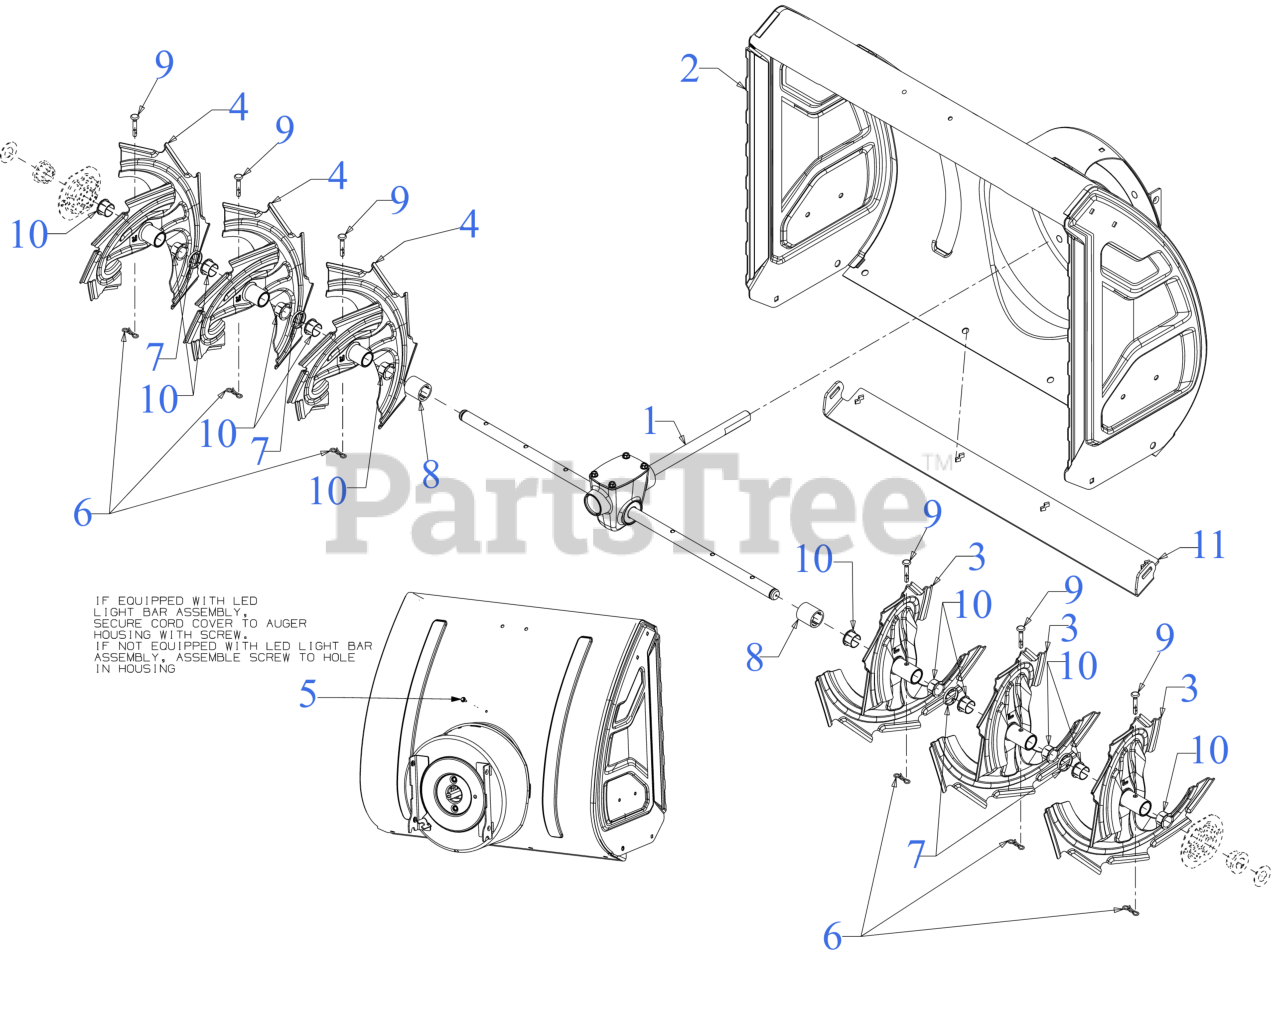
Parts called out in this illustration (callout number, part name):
1	30" AUGER GEARBOX ASSEMBLY
2	30" AUGER HOUSING ASSEMBLY HD W/LED
3	10T AUGER SPIRAL (LH)
4	10T AUGER SPIRAL (RH)
5	SCREW M6-1 x .625
6	BOW TIE COTTER PIN 1/4-5/16
7	SPCR 1.25 OD x 75IDX2.00LG
8	SPACER 1.25OD x .75ID x 1.312 LG
9	SHEAR PIN .25 x 1.50 GR2
10	FLANGE BUSHING
